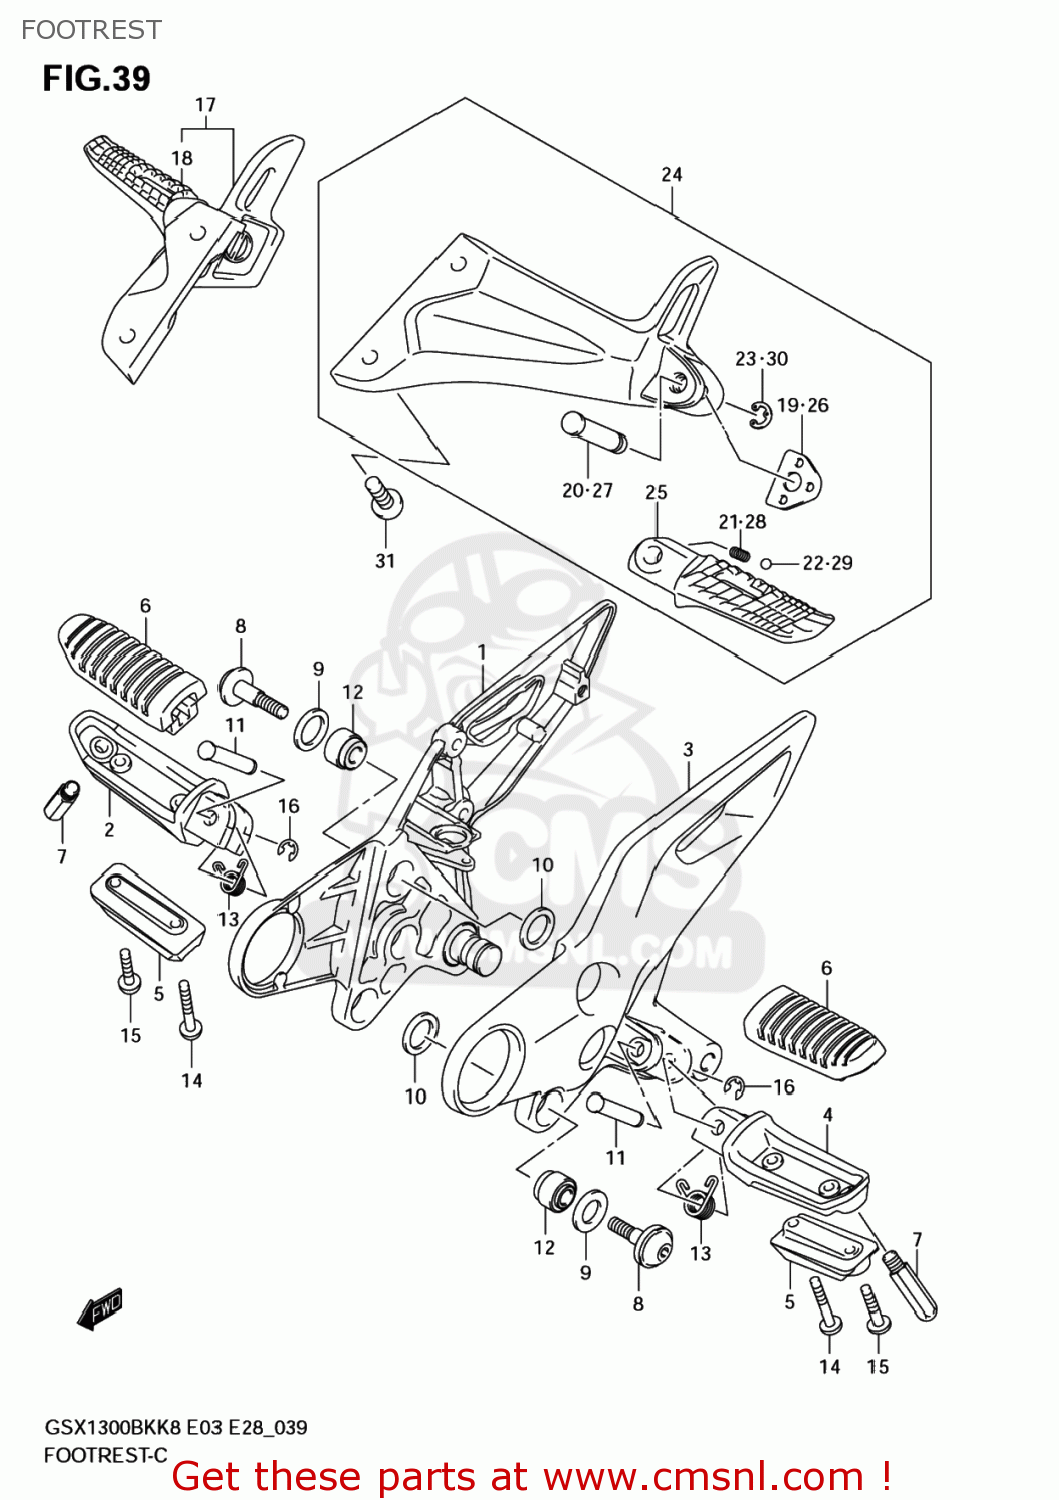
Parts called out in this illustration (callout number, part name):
1	BRACKET,FR FOOTREST,R
2	BAR,FR FOOTREST,R
3	BRACKET,FR FOOTREST,L
4	BAR,FR FOOTREST,L
5	BALANCER,FR FOOTREST
6	RUBBER,FOOTREST BAR
7	BOLT,BANK SENSOR
8	BOLT(8X30)
9	WASHER(13.7X24X2)
10	WASHER(17.2X24X2.2)
11	PIN
12	BUSH(8.4X20X16)
13	SPRING
14	SCREW
15	SCREW
16	E RING
17	FOOTREST ASSY,PILLION,R
18	BAR,PILLION FOOTREST,R
19	PLATE,PILLION FOOTREST
20	PIN
21	SPRING
22	BALL
23	E RING
24	FOOTREST ASSY,PILLION,L
25	BAR,PILLION FOOTREST,L
26	PLATE,PILLION FOOTREST
27	PIN
28	SPRING
29	BALL
30	E RING
31	BOLT(8X23)
